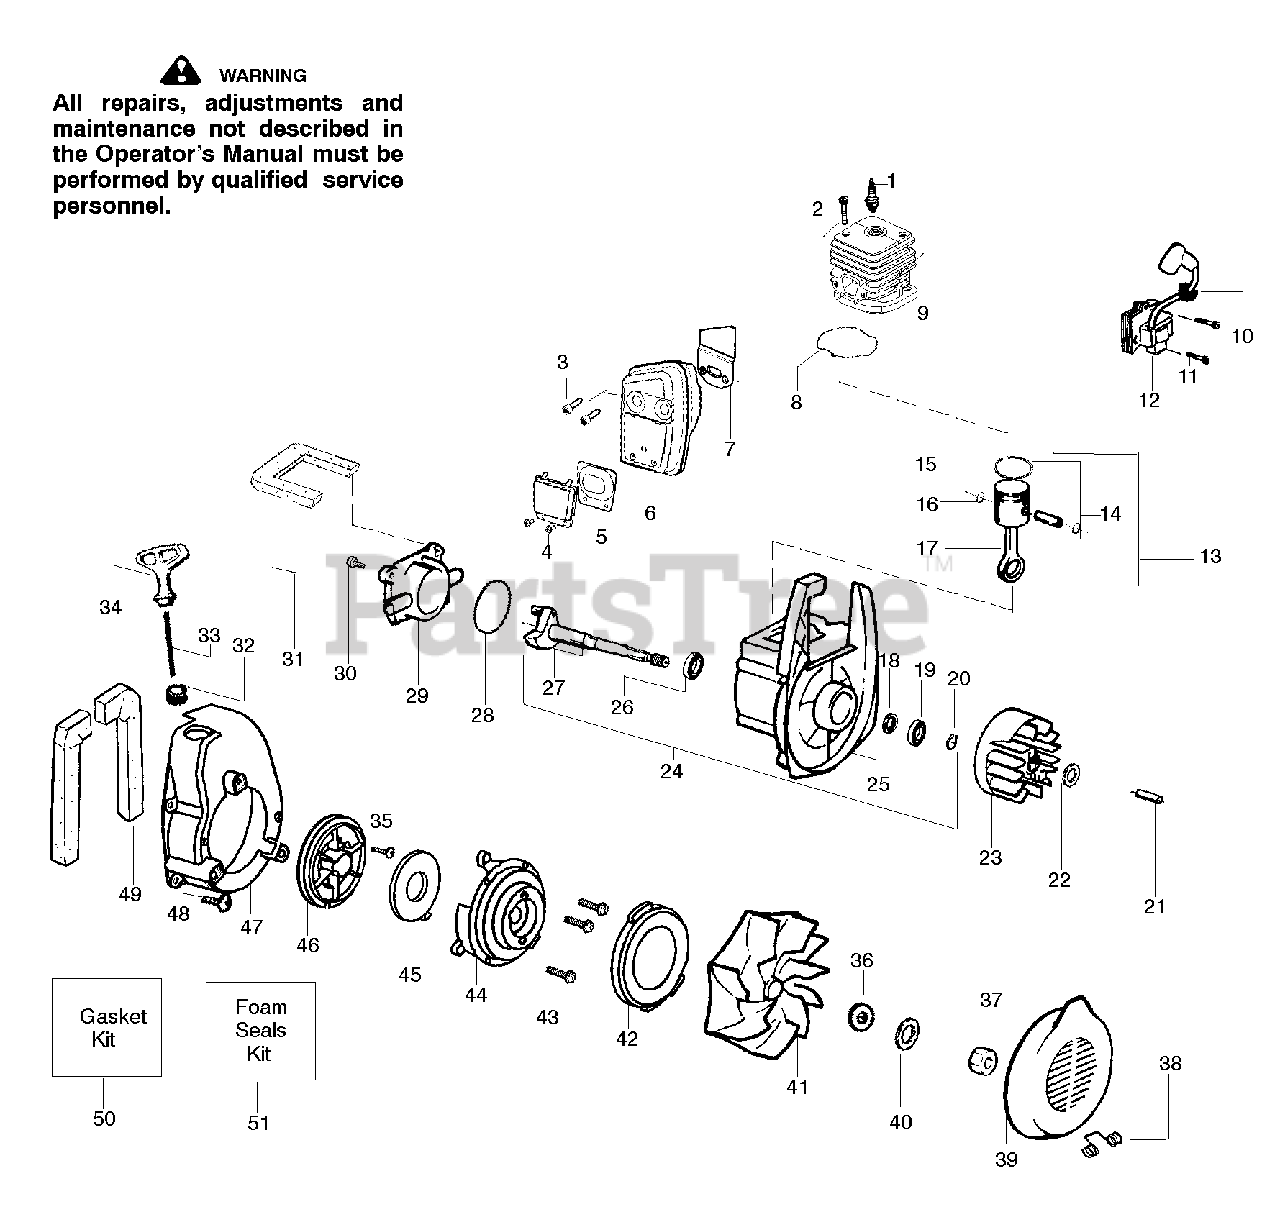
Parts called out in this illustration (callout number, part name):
1	Spark Plug (RCJ-6Y)
3	Screw-Muffler-Internal
5	Kit-Spark Screen
6	Kit-Muffler
7	Gasket-Baffle (kit)
8	Gasket-Cylinder (kit)
9	Kit-Cylinder
10	Grommet-Ign. Module
11	Screw-Ignition Module
12	Ignition Module
13	Kit-Piston/Rod
14	Kit-Piston
15	Piston Ring
16	Retainer-Piston Pin
17	Assy-Connecting Rod
18	Seal-Crankcase
19	Bearing-Outer
20	Retainer Ring-C'chaft
21	Spacer-Flywheel
23	Assy-Flywheel
24	Assy-Crankcase/Crank shaft
25	Assy-Crankcase
26	Bearing-Inner
27	Assy-Crankshaft
28	O-ring-C/case (kit)
29	Cover-Crankcase
30	Screw
31	Foam-219mm (kit)
32	Eyelet-Flange
33	Kit-Rope
34	Handle-Starter
35	Screw-Rope
36	Washer-Belleville
38	Spring-Return Cover
39	Inlet Door
41	Kit-Impeller Assy.
42	Seal-Ring
44	Housing-Pulley
45	Spring-Starter
46	Kit-Starter Pulley
47	Fan Housing
48	Screw
49	Foam-182mm (kit)
50	Kit-Gasket
51	Kit-Foam Seals
